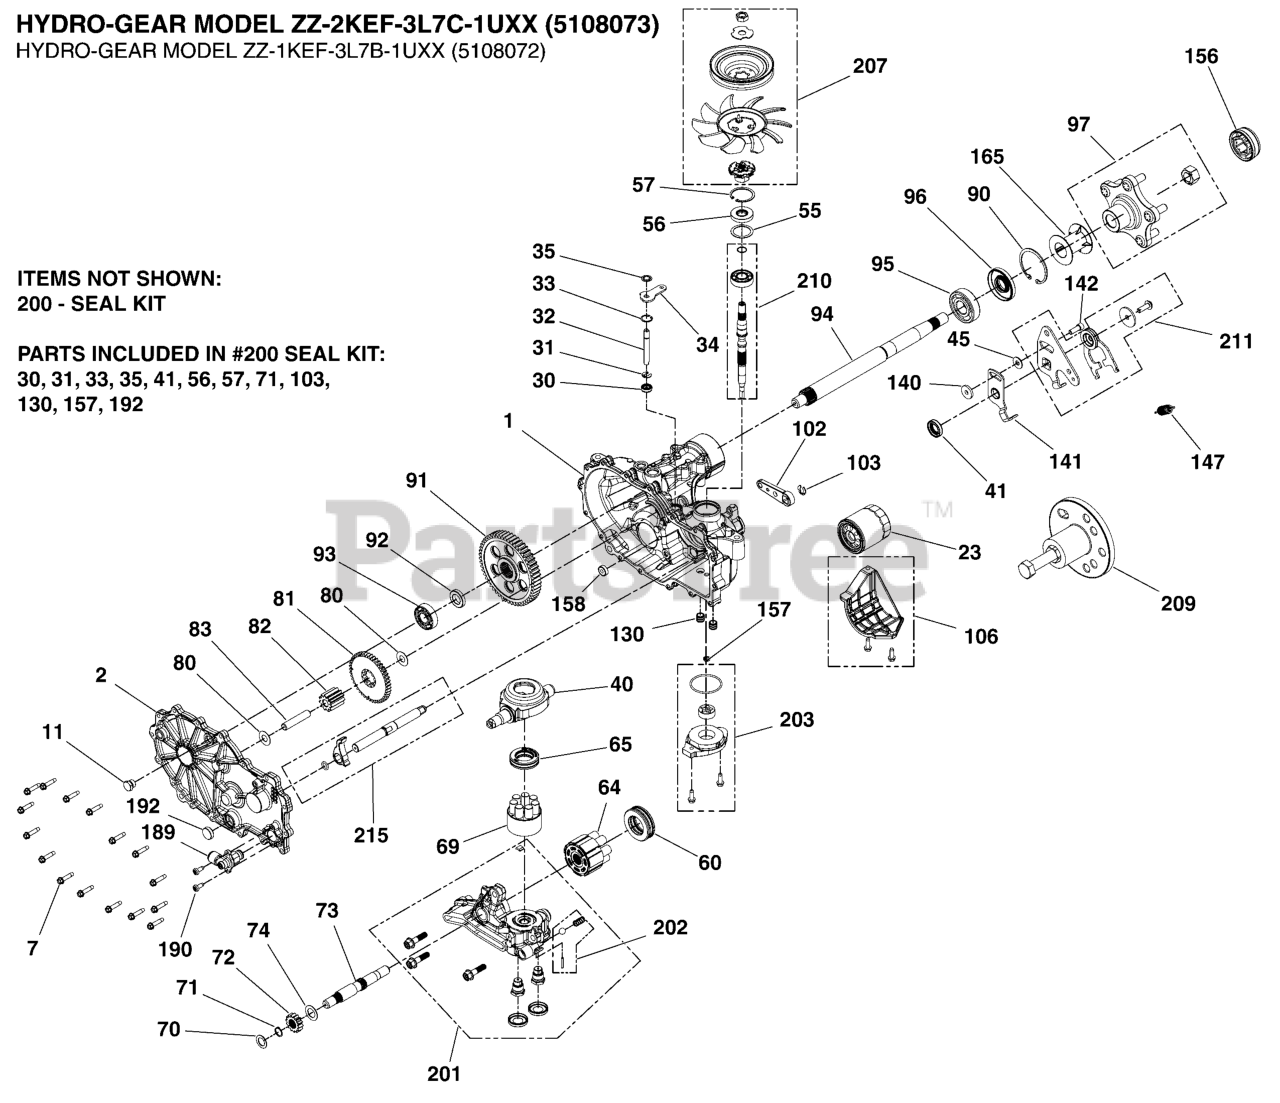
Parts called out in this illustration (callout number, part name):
1	KIT, HOUSING, MAIN, LH, CHARGE, CONTROL
2	KIT, COVER, SIDE, LH, COOLER
7	SCREW, HEX WASHER
23	FILTER, OIL, ZT2800
30	SEAL, LIP .375 X .75 X .25 (55232)
34	ARM, BYPASS
35	RING, RETAINING .375 EXTERNAL
40	SWASHPLATE, TRUNNION
41	SEAL, CONTROL ARM, 18X32X7, #51140
55	SPACER (50951)
56	Lip Seal 17 x 40 x 7 PTC
57	Spacer
64	KIT, 16cc CYLINDER BLOCK ASSEMBLY STEAM TREAT
65	BEARING, THRUST PLASTIC CAGE
70	WASHER, .63 X 1.00 X .05 FLAT
71	RING-SNAP (44145)
72	GEAR, 14T (STEEL)
73	SHAFT, MOTOR
74	WASHER, .71 X 1.16 X .04 FLAT
80	WASHER, .51 X 1.00 X .03 FLAT
81	GEAR, 45T STEEL
82	GEAR, 11T (STEEL)
83	PIN, JACKSHAFT
90	RING, RETAINING 244 INTERNAL (55176)
91	GEAR, 54T FORGED
93	BEARING, BALL 19.05X47.00X14.00 (54554)
94	SHAFT, AXLE
95	BEARING, 25.4 X 62 X 17, 6305R (55173)
96	SEAL, 1.00 X 2.44 X .375 LIP (55175)
97	HUB, ZT3400, 71691
102	HANDLE, ACTUATING
103	E-CLIP, BRAKE ARM, ZT3100 & ZT3400
106	KIT, FILTER GUARD
130	TUBE, CHARGE TRIPLE O-RING
141	ARM, NEUTRAL, LH
142	SHCS, 5/16-24 X .875 (PATCH)
147	SPRING, EXTENSION (51833)
157	KIT, GEROTOR SEAL
158	MAGNET
165	DEBRIS GUARD HG #53496
189	ASSEMBLY, AUX COOLER PORT (#55672)
200	KIT, SEAL, ZT-3800 (73000)
201	KIT, CENTER SECTION, LH CHARGE
202	KIT, CHARGE RELIEF
203	KIT, CHARGE PUMP (72795)
207	FAN & PULLEY KIT, ZT3400'S, STAND-ON
209	KIT, HUB PULLER
210	KIT, INPUT SHAFT (BEARING AND SHAFT ONLY)
211	KIT, L.H. Control Arm
215	KIT, OUTBOARD, RH ROT B/LH ROT A (72960)
